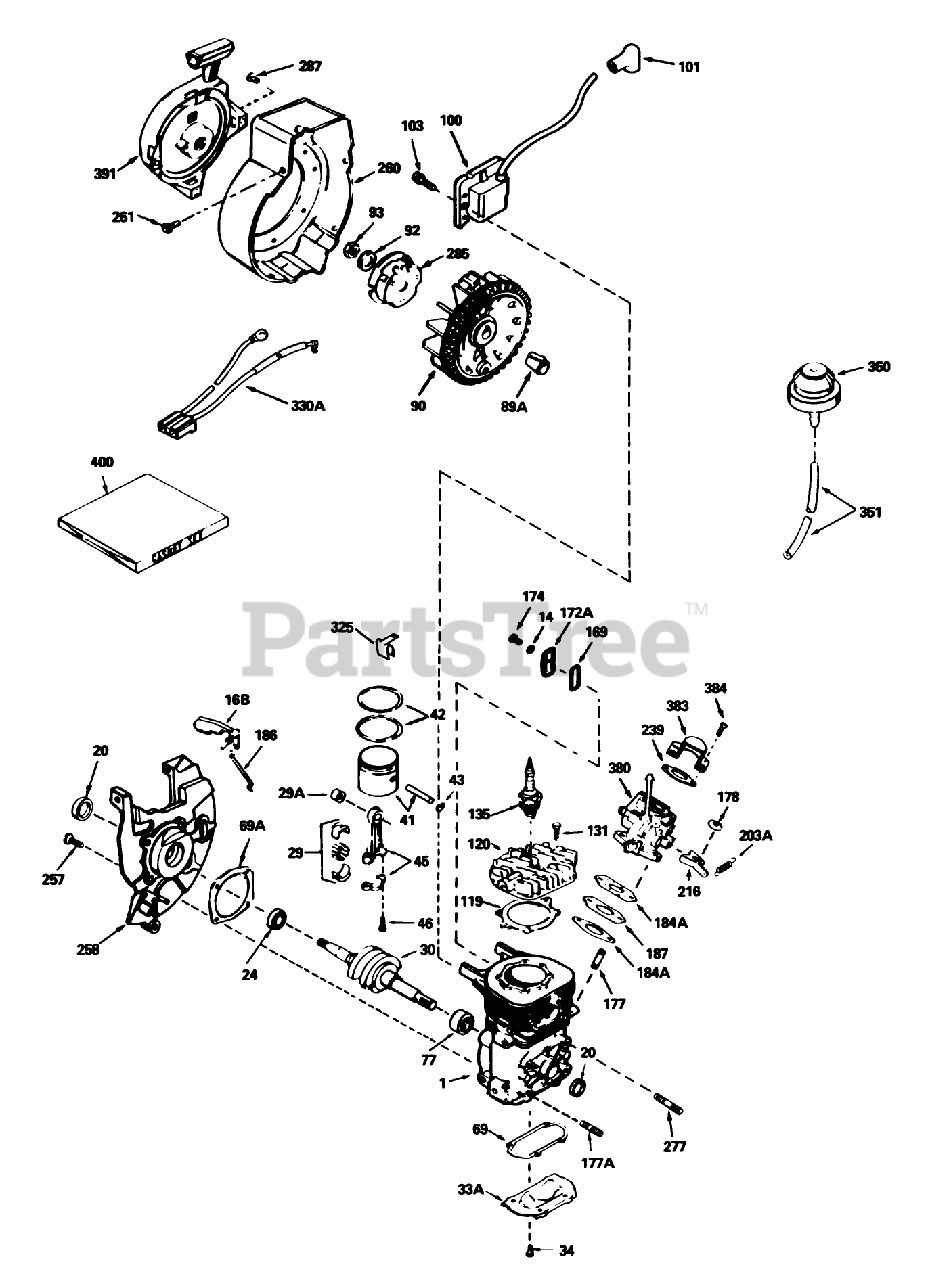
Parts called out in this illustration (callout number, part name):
1	Cylinder Block Assembly (Order Shot Block)
14	Washer
16B	Vane-Air
20	Seal-Oil
24	Bearing-Ball
29	Needle Bearing and Liner Set (37 Needles)
29A	Bearing-Cartridge
30	Crankshaft
33A	Plate-Cover
34	Screw (T-25, 10-24 x 1/2)
41	Piston (Incl. Ref. #43)
42	Ring Set
43	Ring-Retaning
45	Rod Assy.-Connecting (Incl. Ref. #3, 3A 3B)
46	Bolt-Rod, Connecting
69	Gasket-Cover
69A	Gasket-Cover, Cylinder
77	Bearing-Cartridge
89A	Blade (20 inch)
90	Flywheel
92	Washer-Belleville
93	Nut-Flywheel
100	Solid State
101	Cover-Spark Plug
103	Screw
119	Gasket-Head, Cylinder
120	Head-Cylinder
131	Screw (T-30, 1/4-20 x 3/4)
135	Spark Plug-Resistor (R C J 8Y)
169	Cover-Compression, Release
172A	Comp. Release Cover
174	Screw (T-25, 10-24 x 1/2)
178	Locknut
184A	Gasket-Carburetor
186	Link-Governor
187	Spacer
203A	Spring-Governor
216	Lever-Adjusting, Rpm
239	2060A77 WIZARD ROTA
257	Screw (T-30, 1/4-20 x 5/8)
258	Base Assy.-Blower Housing (Incl. Ref. #10)
260	Housing-Blower
261	Screw (1/4-20 x 1/2)
285	Cup-Starter
287	Rivet-Pop
325	Clip-Wire
330A	Harness-Wire
350	Primer Assy.
351	Line-Primer
380	Carburetor (Incl. Ref. #40)
383	Baffle-Carburetor
384	Screw
391	Starter-Rewind
400	Gasket Set
